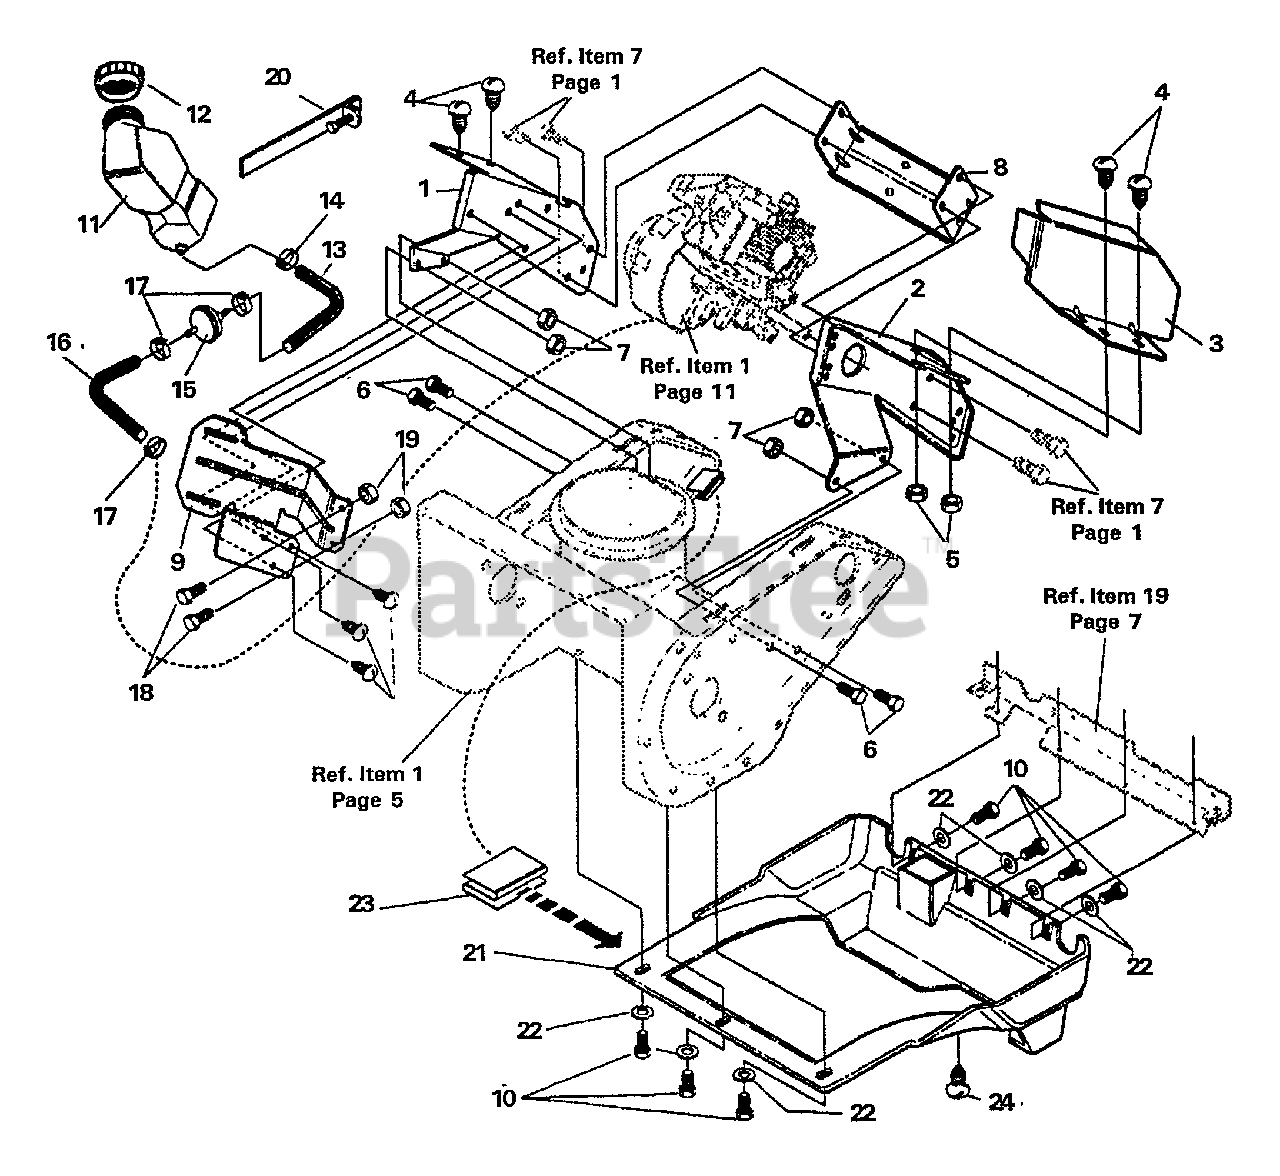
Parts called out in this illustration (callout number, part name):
1	PLATE, REAR MOUNT -- RIGHT
2	PLATE, REAR MOUNT -- LEFT
3	SHIELD, HEAT
4	SCREW
5	NUT, 1/4"-20
6	SCREW - 5/16-18 X0.50" -- HEX HEAD CAP
7	NUT, 5/16"-18
8	SUPPORT, FRAME
9	BRACKET, FUEL TANK
10	SCREW - 10-24×0.63" -- PAN HEAD
11	TANK, FUEL
12	CAP, FUEL
13	TUBING, GAS LINE 8"
14	CLAMP, HOSE
15	FILTER
16	TUBING, GAS LINE 30"
17	CLAMP, HOSE
18	SCREW - 10×24×0.50" -- HEX HEAD MACHINE
19	NUT
20	CLAMP, WORM DRIVE
21	SHROUD, BOTTOM
22	WASHER
23	CLIP
24	SCREW - 10-16×0.50"
